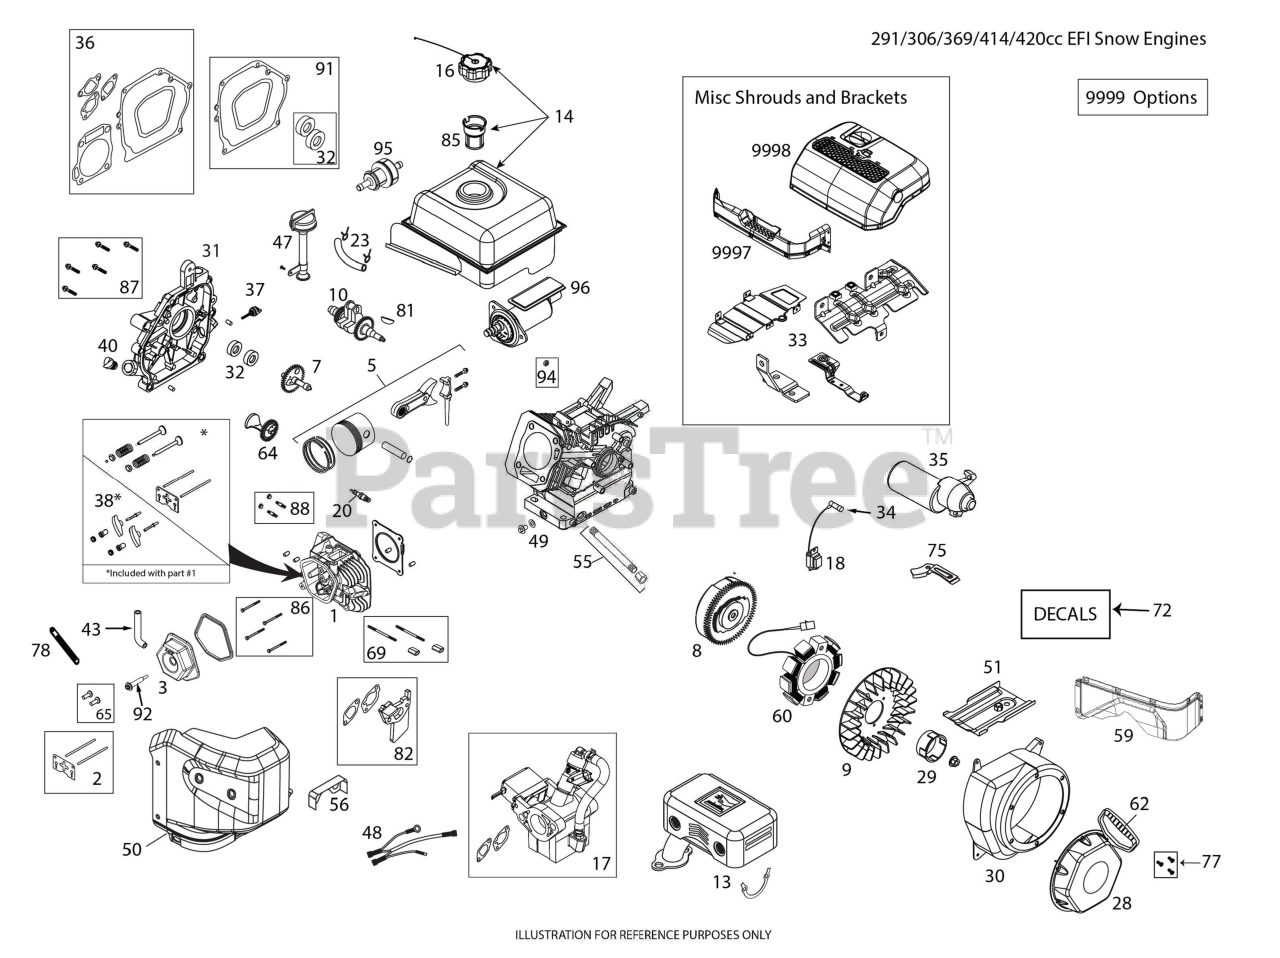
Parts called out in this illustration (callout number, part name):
2	PUSH ROD TAPPET KIT
3	VALVE.COVER.LCT.414CC.
7	CAMSHAFT(SK4141600)
8	FLYWHEEL.EL.ST.SKSN4408.1
9	FLYWHEEL.FAN(SK4144000)
10	Crankshafts
18	IGNITION.COIL.(CDI).291-414CC
20	SPARK.PLUG(SK2911550)
20	PLUG.SPARK
23	Fuel Hoses
29	STARTER CUP
32	OIL SEAL KIT NON-GENERATOR
33	Plates
34	SPARK.PLUG.BOOT.SNW,SKSN4691.1
36	KIT.ENGINE GASKET.LCT.414CC
37	DIPSTK.OIL.BLK.LCTSK4143711.1
38	ROCKER ARM KIT
40	NONREMVABLE.OIL.PLUG(SK4143715
43	TUBE.BREATHER.LCT.219CC/414CC
49	KIT.OIL.DRAIN.PLUG(SK2089911
50	Covers
51	SHIELD.CYLINDER.SNOW(SK4141010
55	OIL PIPE DRAIN EXTENDED.LCT SK
60	Charging Station
62	STARTER.GRIP.SNOW.LCT.SKSN0603
64	COUNTER WEIGHT KIT
65	TAPPET KIT.LCT.SK2911005.1
69	STUD.CARB.MOUTING.KIT.414CC
75	SHIELD.U/FYWHL.CHARG(SKSN4604)
77	BOLT.KIT.RECOIL.LCT.ALL.ENGINE
78	STRAP.RETAINING.TUBE.BREATHER.
81	KEYS.FLYWHEEL.208/414CC.5PACK
82	SPACER.CARBURETOR.414CC.LCT
85	STRAINER.FUEL.TANK.LCT.208CC
86	KIT.BOLT.CYLINDER.HEAD.(4PC)
87	KIT.BOLT.CRANKCASE.COVER.414CC
91	GASKET KIT CRANKSHAFT.LCT
92	CENTER VALVE COVER BOLT
